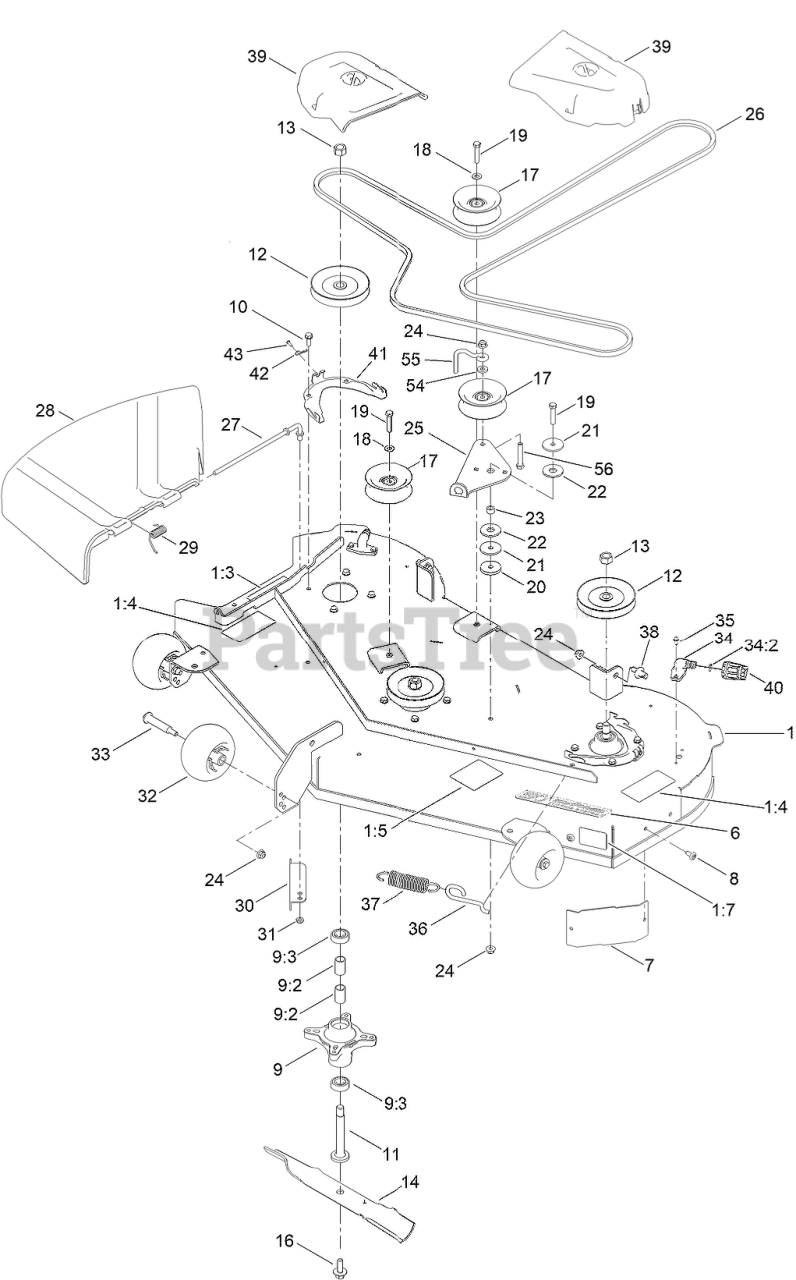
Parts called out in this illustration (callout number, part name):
1	50 INCH DECK AND DECAL ASM
1:3	DECAL-DANGER
1:4	DECAL-DANGER, DECK
1:5	DECAL-ROUTING, BELT
1:7	DECAL-SCALP, ANTI
6	DECAL - DECK
7	BAFFLE-CORNER
9	SPINDLE ASM
9:2	SPACER
9:3	BEARING-BALL
10	SCREW-TAPTITE
11	SHAFT-SPINDLE
12	PULLEY
13	NUT-HEX
14	BLADE-HI LIFT
16	BOLT-BLADE, SEMS
17	PULLEY-IDLER, FLAT
18	WASHER-FLAT
19	SCREW-HH
20	WASHER-PLAIN
21	WASHER-REBOUND
22	WASHER-FRICTION, COMPOSITE
23	SPACER
24	NUT-HF, NI
25	ARM-IDLER
26	V-BELT
27	ROD-PIVOT
28	DEFLECTOR-DISCHARGE
29	SPRING-TORSION
30	BAFFLE-CUTOFF
32	ROLLER-SCALP, ANTI
33	BOLT-SHOULDER
34	FITTING-WASHOUT
34:2	O-RING
35	SCREW-HWH
36	HOOK-RETURN SPRING
37	SPRING-EXTENSION
38	PIN-DECK
39	COVER-BELT
40	CONNECTOR-HOSE
41	BRACKET-COVER, BELT
42	PIN-HAIR
43	SCREW
54	SPACER-HUB, BLOWER
55	BELT GUIDE - IDLER
56	SCREW-HH
